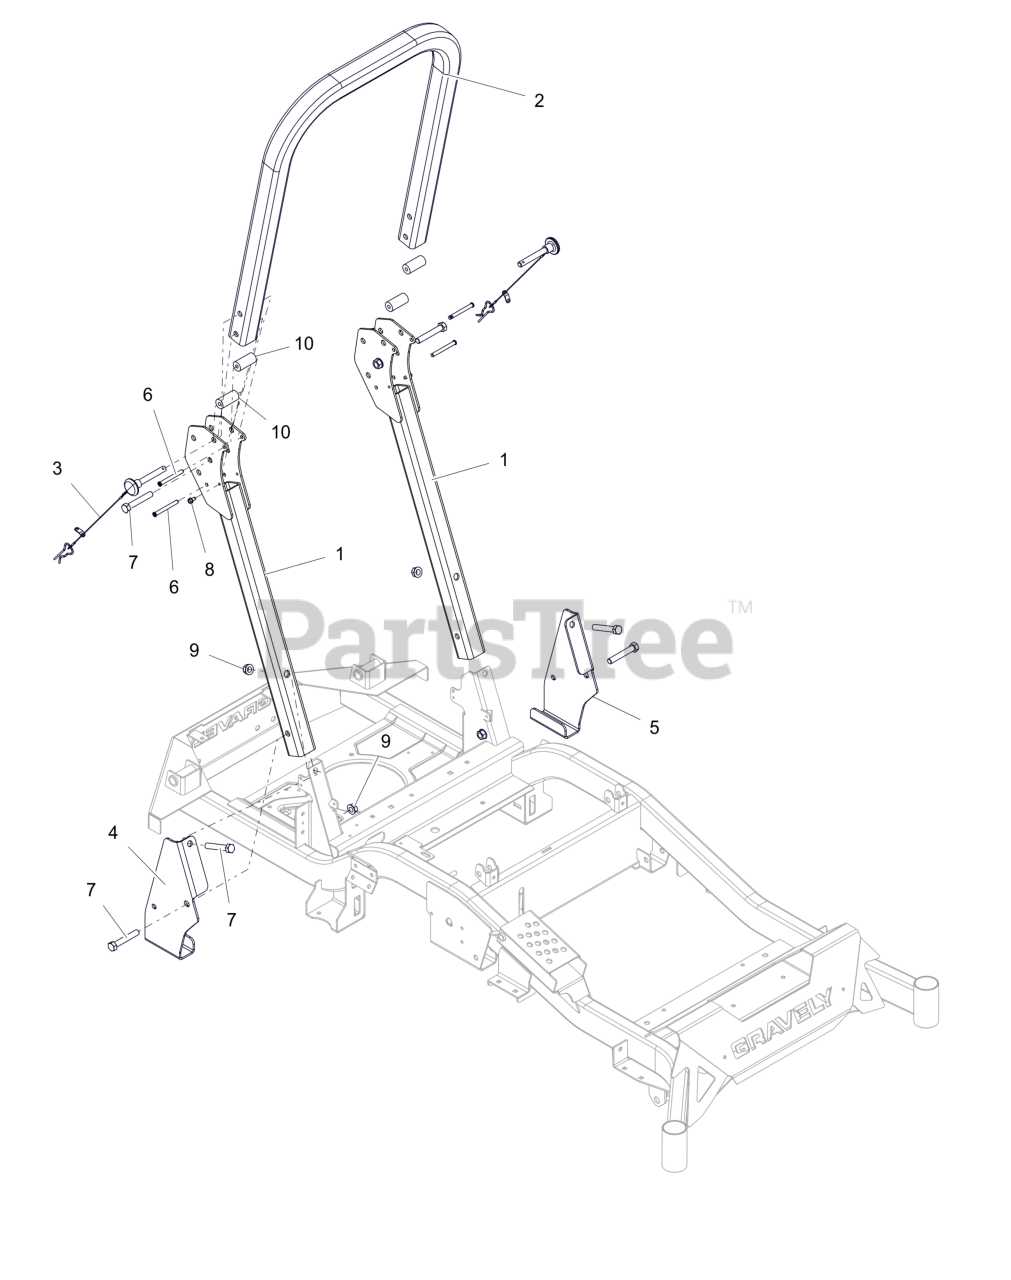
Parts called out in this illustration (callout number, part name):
1	ROPS, REPLACEMENT
2	HOOP, PT Z & ZX ROPS
3	PIN, ROPS W/LANYARD
4	BRKT, ROPS SUPPORT - RH
5	BRKT, ROPS SUPPORT -LH
6	PIN, SLIC .312 X 2.570
7	BLT, HEX .50-13X3.00 G5 ZCC
8	SCR-TAP .25-20X.50 HWH ZCC
9	NUT-LK-CTR-FLG .500-13 GG ZCC
10	BUMPER, ROPS ANTI-VIBRATION
